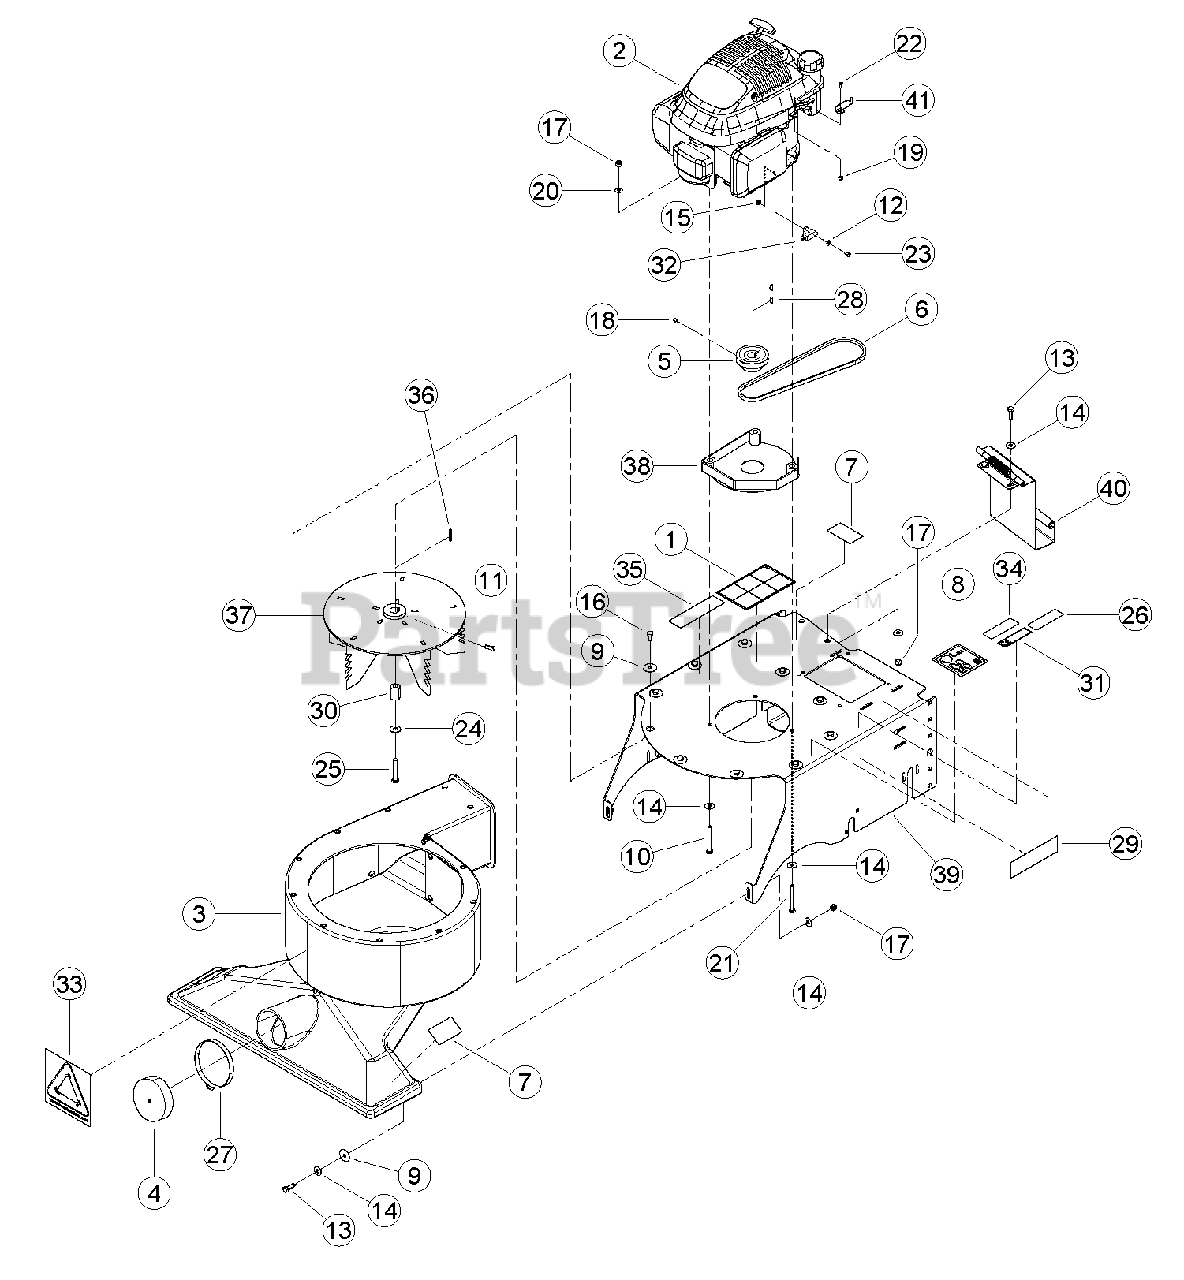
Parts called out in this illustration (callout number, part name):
1	DECAL, PROTECTION
2	ENGINE, 5.5 HP HONDA GCV (WV160S ONLY) (FOR SERVICE SEE ENGINE OWNER'S MANUAL OR YOUR NEAREST AUTHORIZED HONDA INDUSTRIAL ENGINE DEALER)
2	ENGINE, 190CC B&S INTEK/IC VERTICAL (WV190S ONLY) (FOR SERVICE SEE ENGINE OWNER'S MANUAL OR YOUR NEARES AUTHORIZED BRIGGS & STRATTON INDUSTRIAL ENGINE DEALER)
3	ASSEMBLY, FAN HOUSING W/ INTAKE
4	CAP, ROUND VINYL
5	PULLEY, 2.85 O.D. X 7/8 IN BORE
6	BELT, SP BEARVAC
7	DECAL, DANGER
8	DECAL, 98 DB (WV190S ONLY)
9	WASHER, 5/16 FENDER
10	BOLT, 5/16 X 2-3/4 HCPS GR5 (WV190S ONLY)
11	SCREW, 5/16-18 X 5/8 SQ HD SET
12	WASHER, #8 SAE FLAT (WV160S ONLY)
13	BOLT, 5/16 X 1 HEX HD
14	WASHER, 5/16 FLAT
15	NUT, #8 X 32 NYLOCK (WV160S ONLY)
16	BOLT, 5/16 X 5/8 HEX HD
17	NUT, 5/16 NYLOCK
18	SCREW, 5/16 X 3/8 SET
19	NUT, 10/24 NYLOCK TYPE NM ZP (WV160S ONLY)
20	WASHER, 5/16 SAE FLAT
21	BOLT, 5/16 X 4 HHCS GR5 ZP (WV190S ONLY)
22	SCREW, MCH 10-24 X 1/2 PAN HD PH ZP (WV160S ONLY)
23	SCREW, #8 X 32 X 3/4 PAN PHP ZP (WV160S ONLY)
24	WASHER, 3/8 GR8 USS ZP
25	BOLT, 3/8 NC X 2-1/4 HHCS NF GR8 ZP
26	DECAL, SERIAL NUMBER
27	CLAMP, 4 IN HOSE
28	KEY, 3/16 X 5/32 4 MM WDRFF JUMP
29	DECAL, ECHO BEARCAT 6.82 X 1.90
30	SPACER, .88 X 1.25
31	DECAL, 6 HP SP BEARVAC INFORMATION (WV190S ONLY)
32	SWITCH, HONDA ENGINE KILL (WV160S ONLY)
33	DECAL, COLLECT IT
34	DECAL, ATLANTIC BRIDGE LTD INFO (WV190S ONLY)
35	DECAL, MODEL WV160S
35	DECAL, MODEL WV190S
36	KEY, 3/16 X 1-1/4 SQUARE
37	WELDMENT, BEARVAC ROTOR
38	WELDMENT, BEARVAC ENGINE SUPPORT
39	SUPPORT, BEARVAC FRAME
40	ASSEMBLY, EXHAUST DOOR
41	PLATE, HONDA BRACKET HOLDER (WV160S ONLY)
